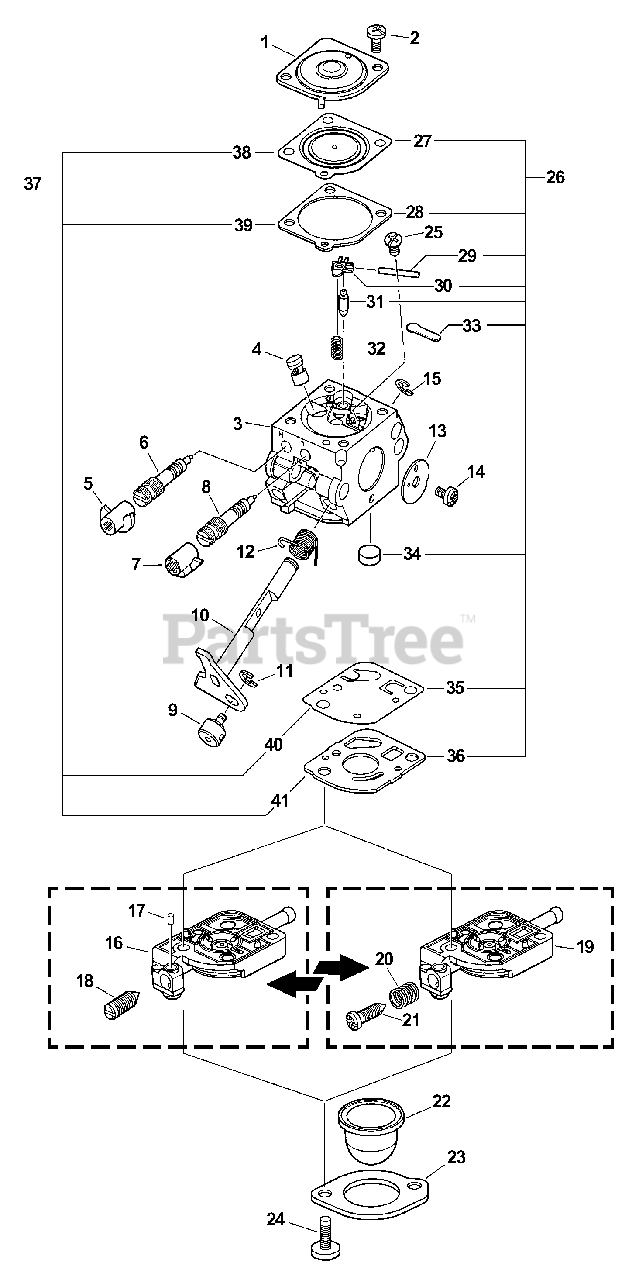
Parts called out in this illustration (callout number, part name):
1	COVER, METERING DIAPHRAGM
3	BODY, CARBURETOR
4	NOZZLE, CHECK VALVE
5	CAP, LIMITER - RED
6	NEEDLE, HIGH SPEED
7	CAP, LIMITER - WHITE
8	NEEDLE, LOW SPEED
10	SHAFT, THROTTLE
12	SPRING, THROTTLE RETURN
13	VALVE, THROTTLE
16	BODY ASSY, PURGE
17	PIECE, FRICTION
18	SCREW, IDLE ADJUST
19	BODY ASSY, PURGE
21	SCREW, THROTTLE ADJUST
22	BULB, PURGE
23	RETAINER
26	REPAIR KIT, CARBURETOR
27	DIAPHRAGM, METERING
28	GASKET, METERING
29	PIN, METERING LEVER
30	LEVER, METERING
31	VALVE, INLET NEEDLE
32	SPRING, METERING LEVER
33	PLUG, WELCH
34	STRAINER
35	DIAPHRAGM, PUMP
36	GASKET, PUMP
37	GASKET / DIAPHRAGM KIT
38	DIAPHRAGM, METERING
39	GASKET, METERING
40	DIAPHRAGM, PUMP
41	GASKET, PUMP
